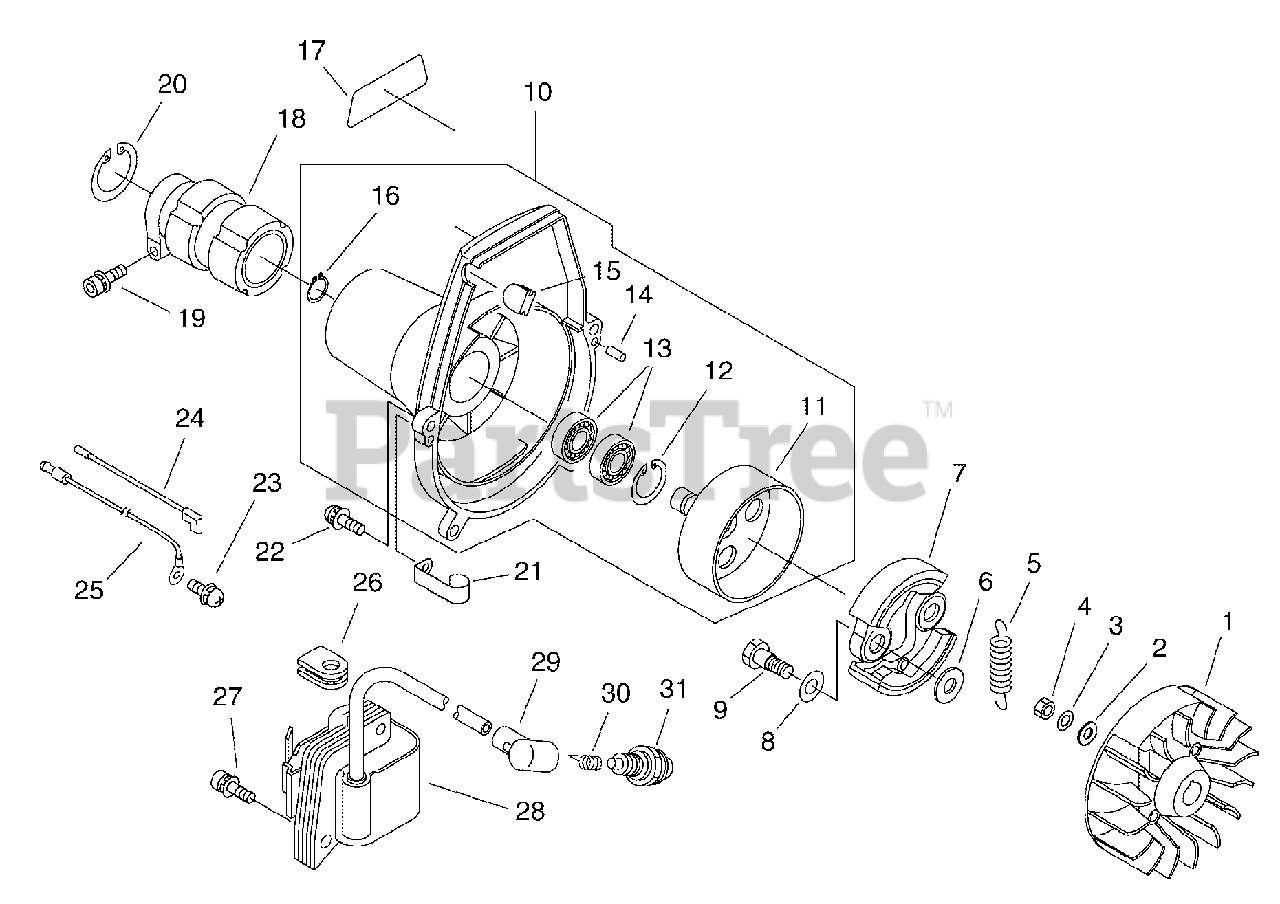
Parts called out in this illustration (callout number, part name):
1	FLYWHEEL
2	WASHER 8.5×16×1.2
3	WASHER, SPRING 8
4	NUT 8×1.25
5	SPRING, CLUTCH
6	WASHER 6.2×19×1.0
7	SHOE, CLUTCH
8	WASHER, SPRING 8.5×16×0.5
9	BOLT, CLUTCH 8×7.9×M6
10	COVER ASSY, FAN
11	DRUM, CLUTCH
12	RING, SNAP 26
13	BEARING, BALL 6000LU
14	PIN, LOCATING 4×8
15	GROMMET, PLUG
16	E-RING 10
17	LABEL, ECHO
18	HOLDER, MAIN PIPE
19	BOLT 5×28
20	RING, SNAP Ø42
22	SCREW 5×18
23	SCREW 5×10
24	LEAD - IGNITION 145 MM
25	LEAD - GROUND
27	BOLT 5×22
28	COIL, IGNITION
29	CAP, SPARK PLUG
30	TERMINAL, SPARK PLUG
31	SPARK PLUG - BPM7A
